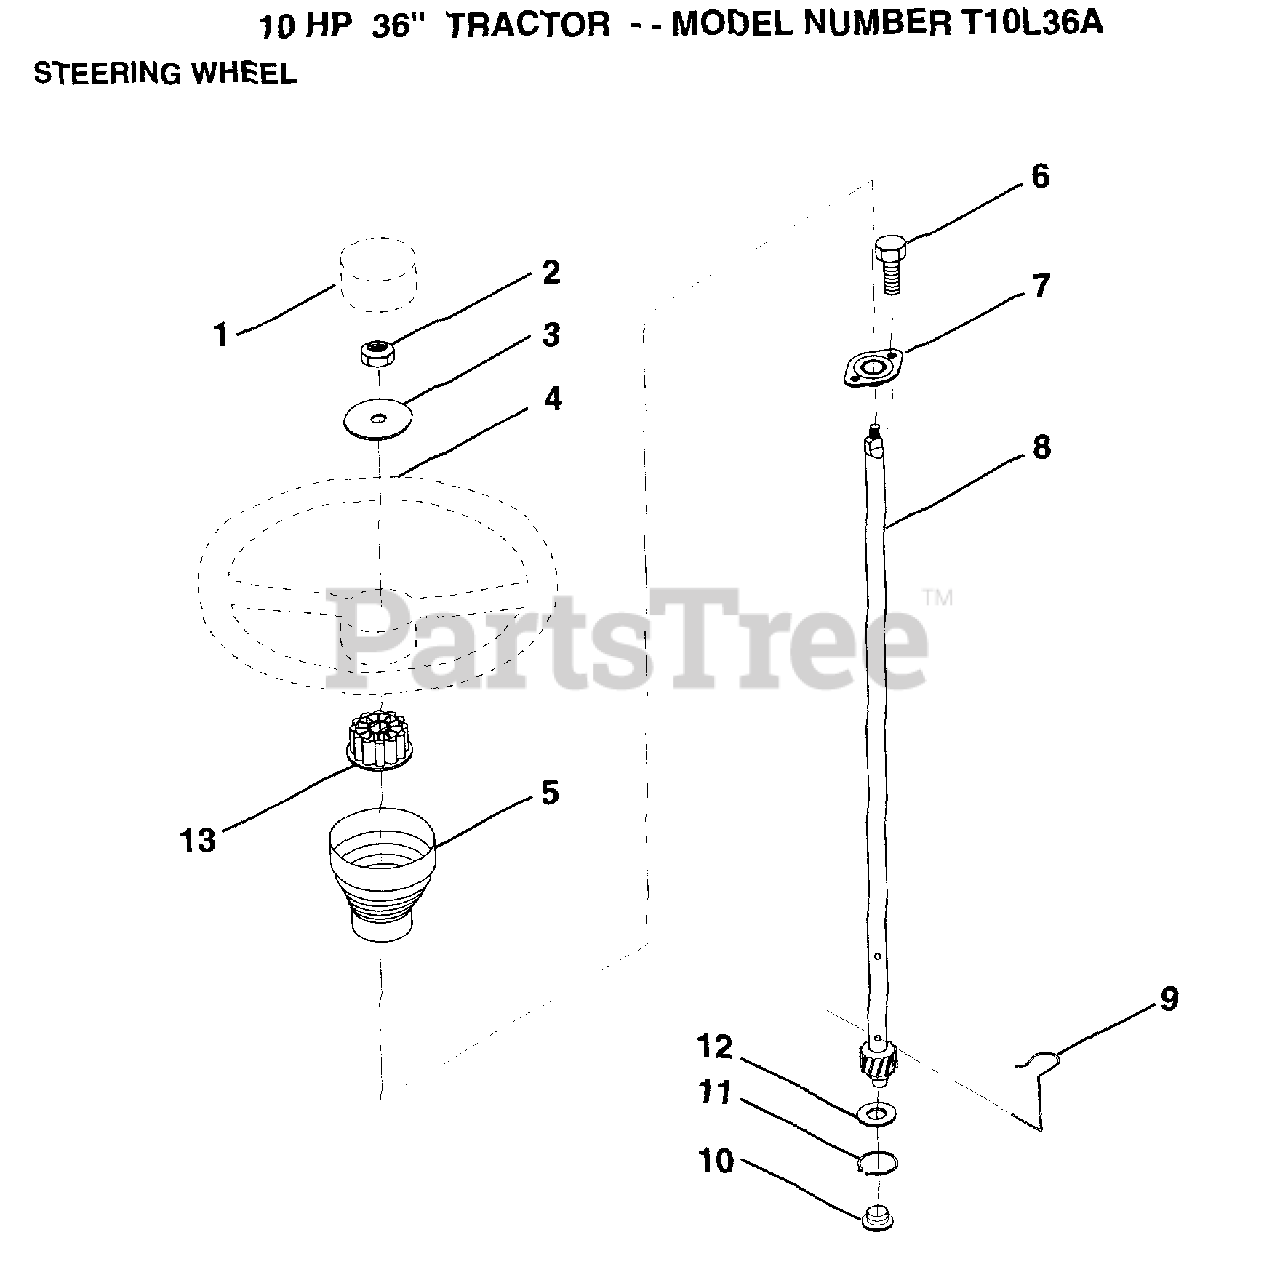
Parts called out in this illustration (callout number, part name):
1	ST WHL INSERT CAP
2	GRIPCO NUT
3	WASHER T
5	SLEEVE STEERING
9	STEERING CLIP
10	BUSHING STEER LWR
11	RING
12	WASHER LT
13	ADAPTER-WHEEL LT
